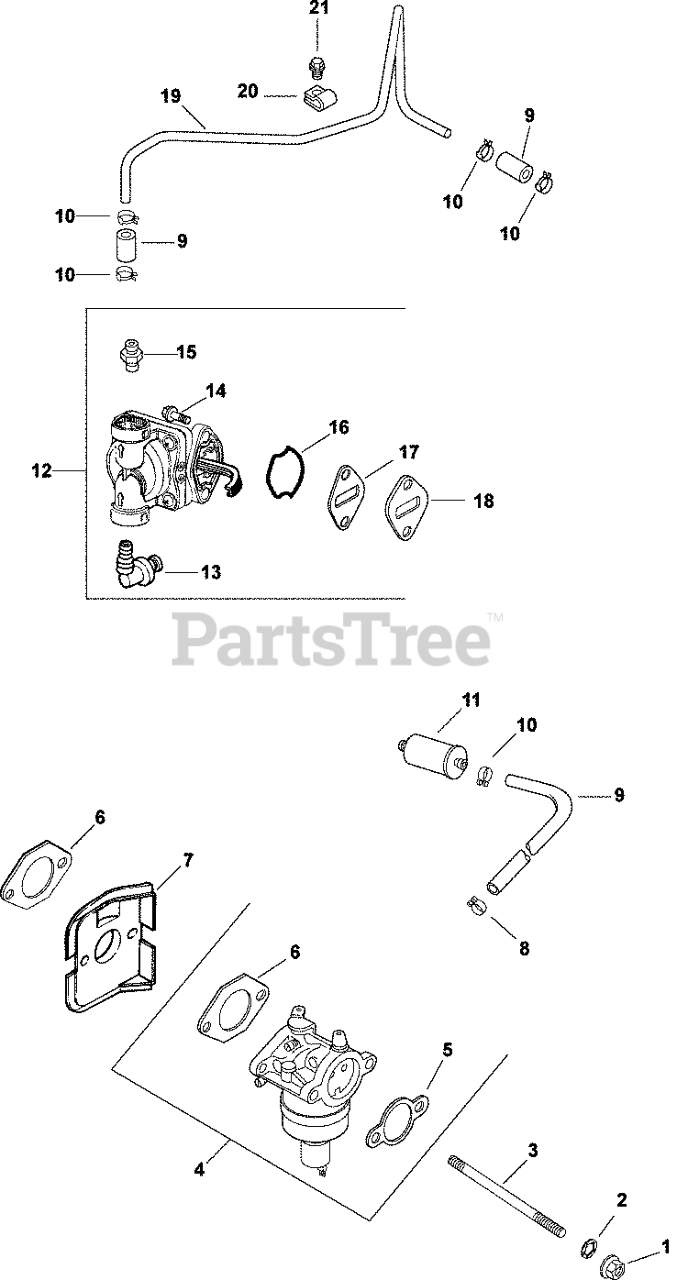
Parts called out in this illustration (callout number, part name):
1	NUT, FLG M6X1.0
2	WASHER, INT TOOTH LOCK 1/4"
3	STUD,M6X1.0X116
4	KIT, CARBURETOR - USE 12 853 178-S
5	GASKET, AIR CLEANER BASE
6	GASKET, CARBURETOR
7	DEFLECTOR, HEAT
8	CLAMP, BAND SPRING HOSE-(#2523737S)
9	HOSE,LW PERM.FUEL 24.00"-USE 25 111 81-S
10	CLAMP, HOSE (KM)-USE 25 237 31-S
11	FILTER,FUEL 51 MICRON (FUEL PUMP)
12	KIT, FUEL PUMP
13	CONNECTOR, 90 DEG. HOSE
14	SCREW, LBD SKT M6x1.0x20-(#25086403S)
15	KIT, STRAIGHT FITTING
16	O-RING, FUEL PUMP
17	GASKET, FUEL PUMP
18	SPACER, FUEL PUMP
19	LINE, FUEL
20	CLIP, TUBE & WIRING (KM)
21	SCREW, FLG THD FRM M5X.8X10
1285368-S	KIT, CARBURETOR W/GASKET
